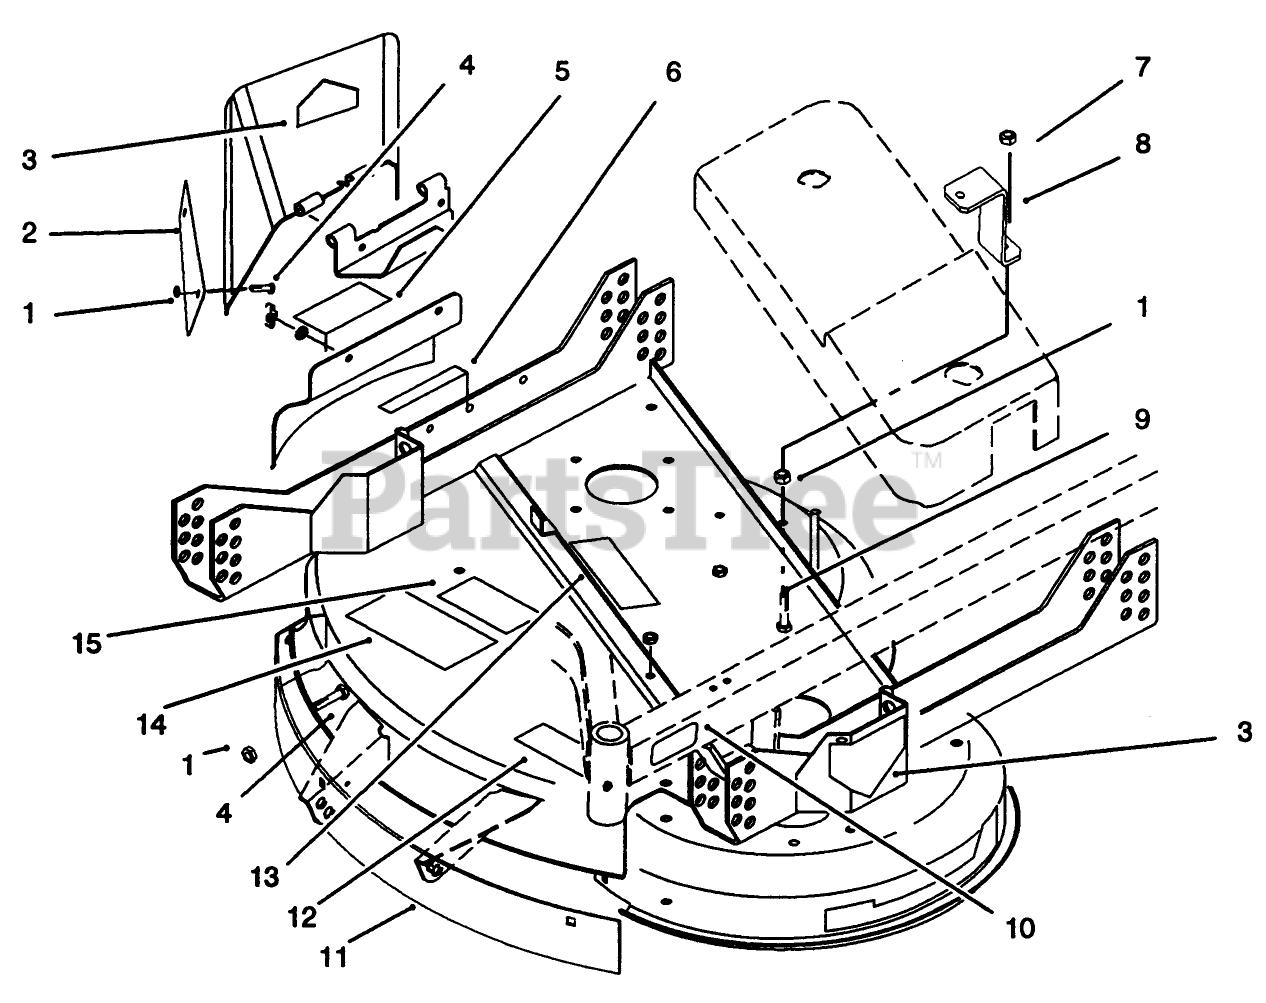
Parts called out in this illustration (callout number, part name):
1	NUT-LOCK, NI
2	Baffle-Deflector
3	DECAL-DANGER
4	SCREW-HH
5	Decal-Danger
6	DECAL - WARNING
7	NUT-HEX
8	BRACKET-DECK, BELT GUARD
9	SCREW-HH
10	DECAL-HOC
11	Baffle-Front
12	SEAL KIT
13	DECAL-DANGER
14	DECAL-HEIGHT OF CUT
15	DECAL-TORQUE, BLADE BOLT
